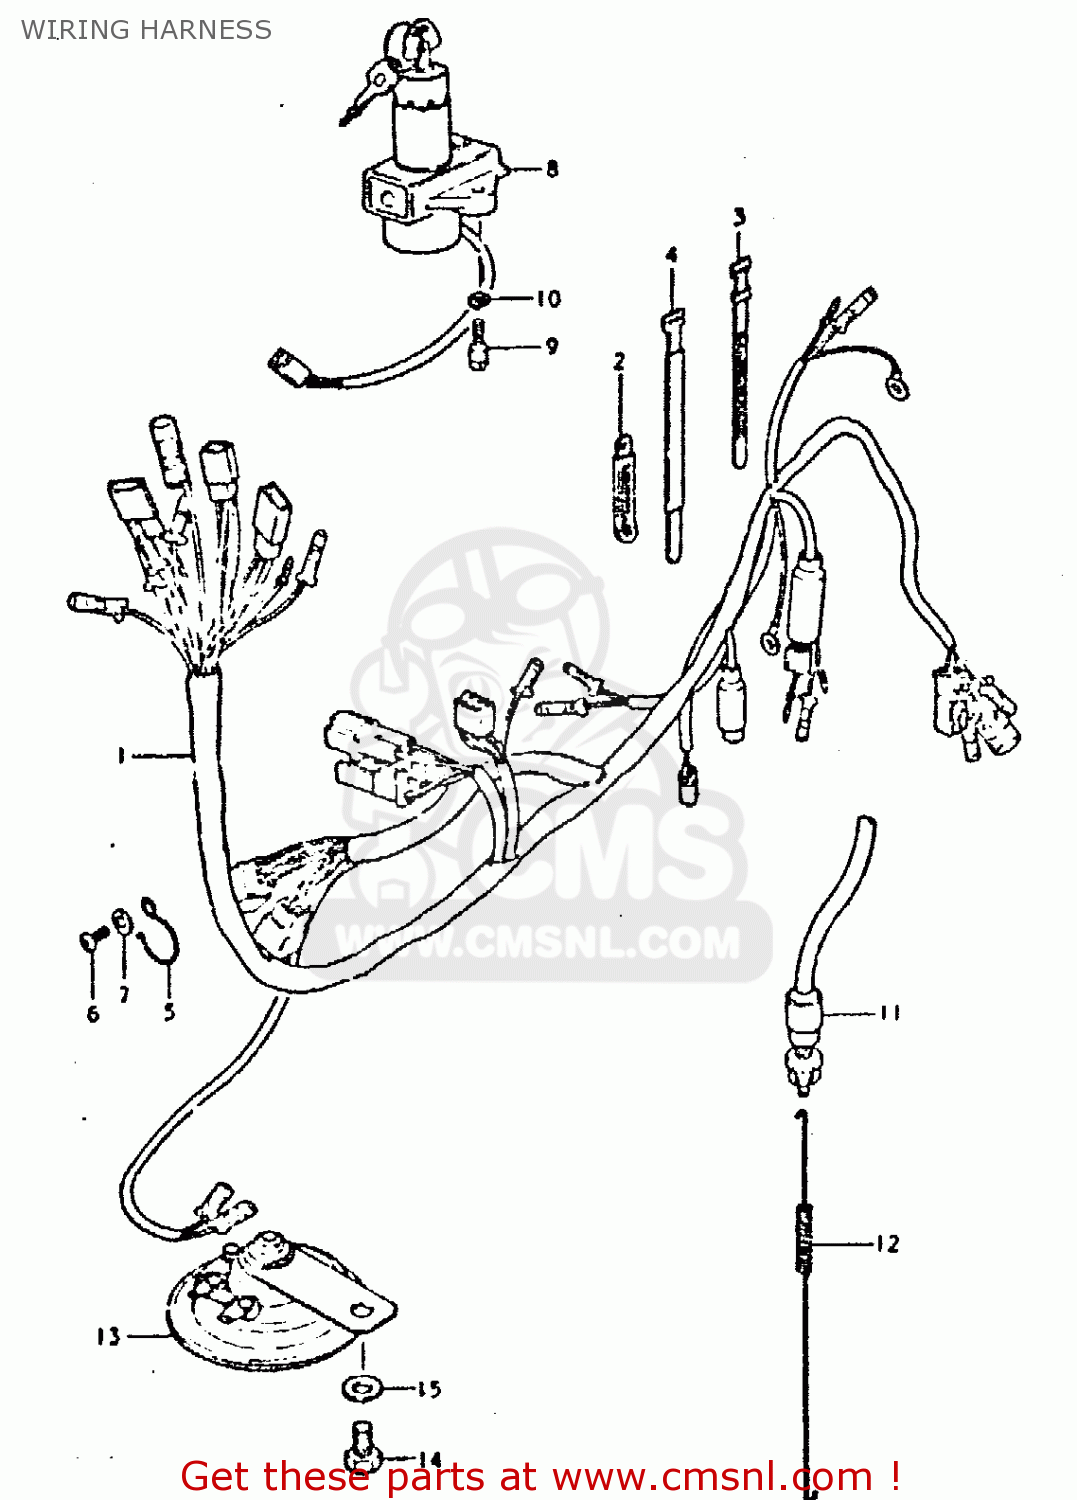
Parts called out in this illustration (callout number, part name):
1	WIRING HARNESS
2	CLAMP
3	CLAMP(L:80)
4	CLAMP
5	GUIDE,WIRING HARNESS
6	SCREW 6X12
7	WASHER 6MM
8	LOCK ASSEMBLY,STEERING
9	BOLT
10	LOCK WASHER
11	SWITCH ASSEMBLY,STOP LAMP
12	SPRING
13	HORN ASSEMBLY
14	BOLT 8X12
15	WASHER
